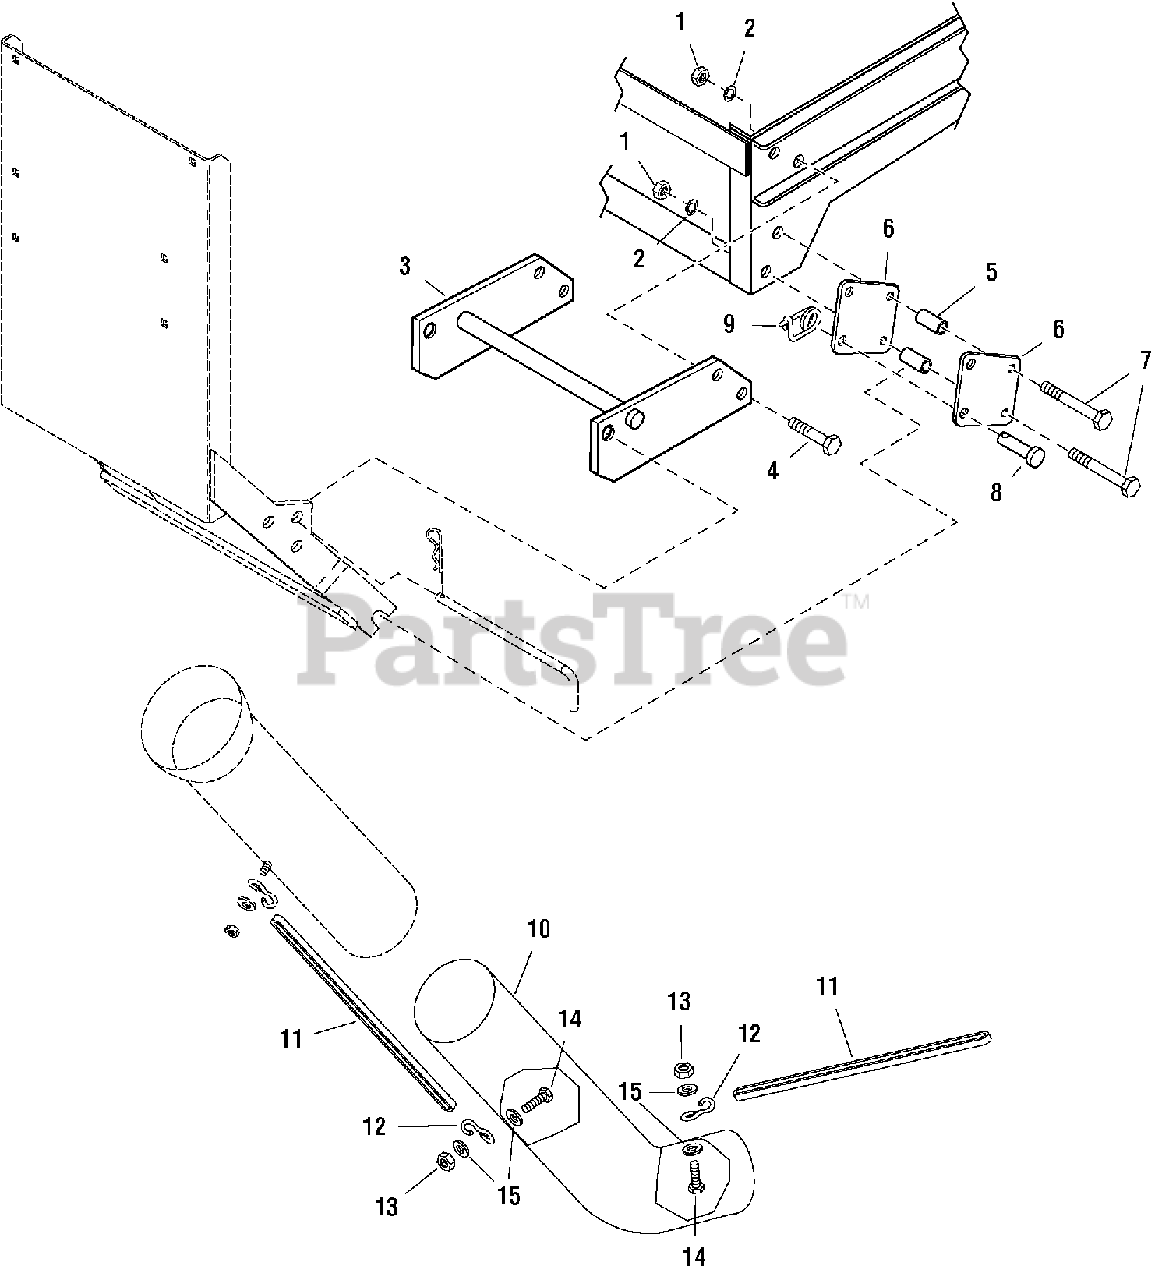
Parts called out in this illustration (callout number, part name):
1	NUT, Hex, 1/2-13
2	LOCKWASHER, 1/2
3	HITCH ASSEMBLY
4	CAPSCREW, Hex Head, 1/2-13 x 1-1/4
6	PLATE, Lower
7	CAPSCREW, Hex Head, 1/2-13 x 2-1/2
8	PIN, Clevis
9	RETAINER PIN, Spring
10	CHUTE, Lower
11	STRAP, Rubber, Black
13	LOCKNUT, Hex, ESNA Light, 1/4-20
14	CAPSCREW, Hex Head, 1/4-20 x 1-1/4
15	WASHER, 1/4
